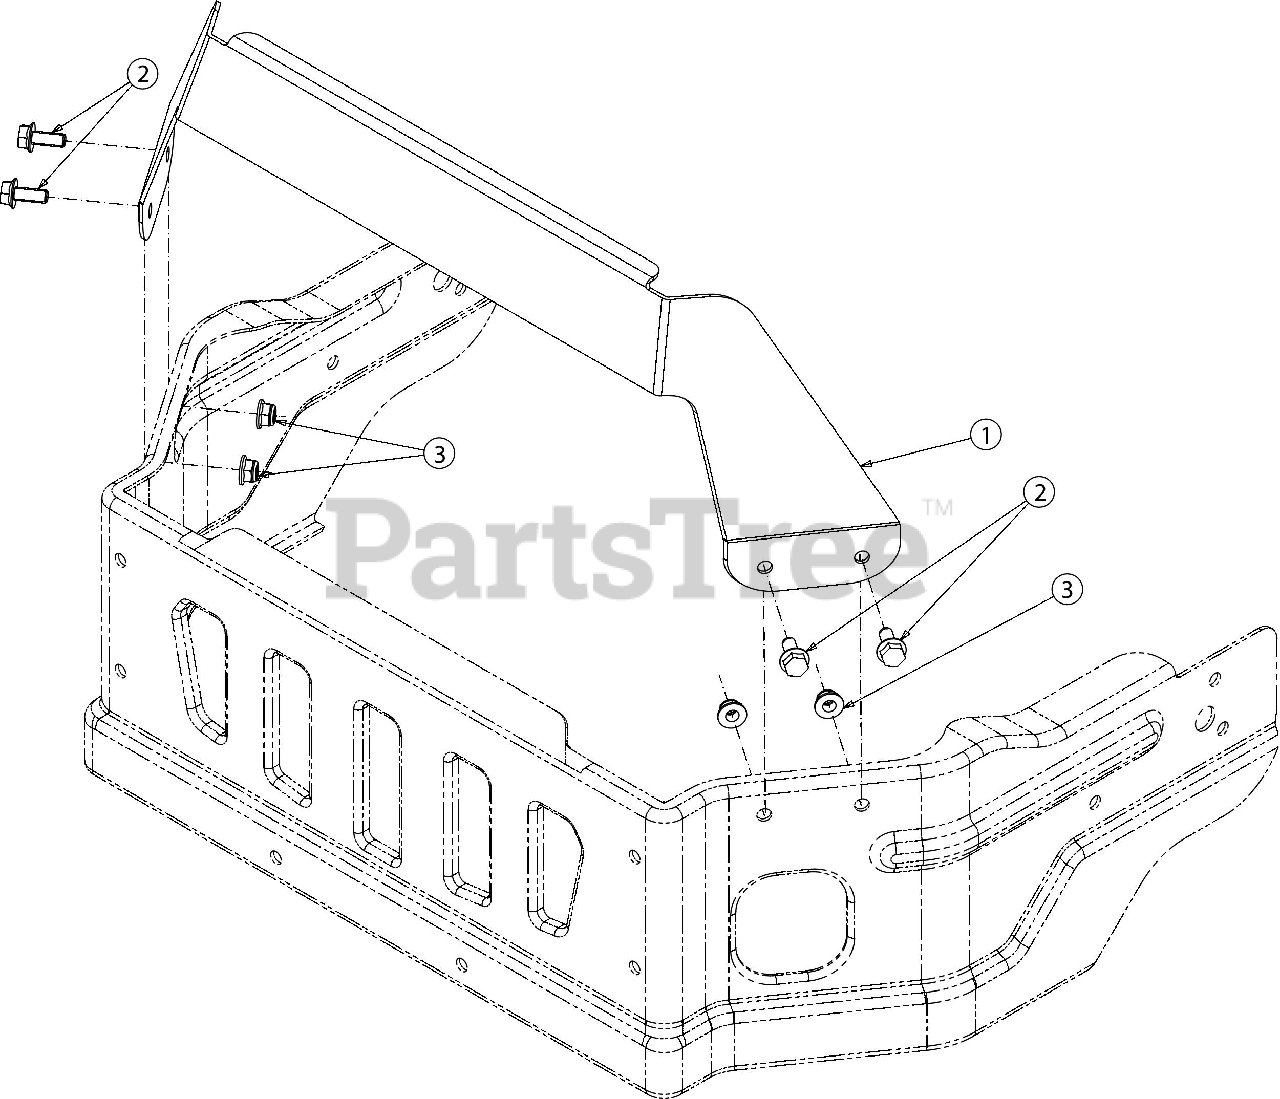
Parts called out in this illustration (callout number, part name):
1	UPPER BUMPER BRACKET
2	SCREW 5/16-18
3	FLANGE LOCK NUT 5/16-18
